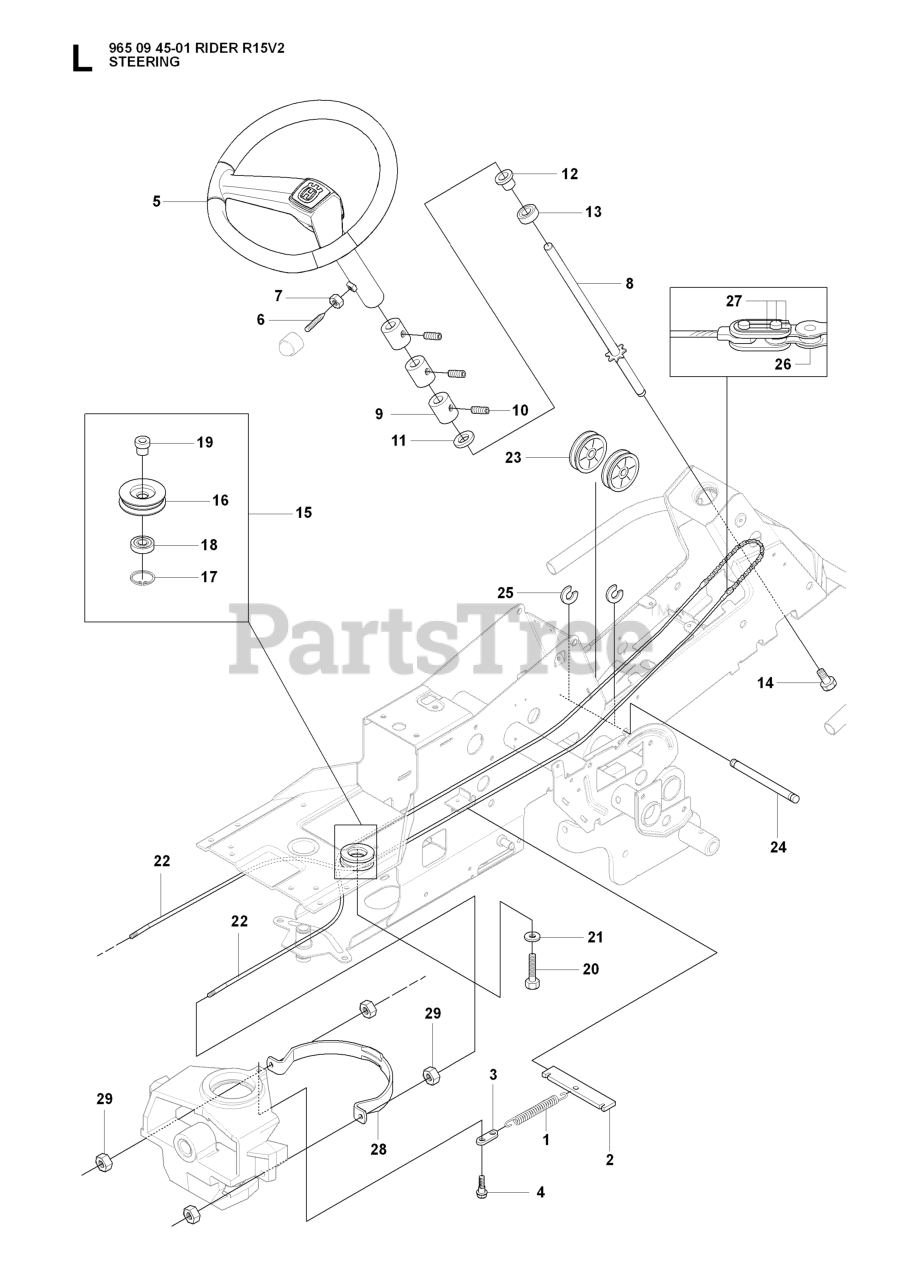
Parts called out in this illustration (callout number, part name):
2	SPRING BRACKET
5	STEERING WHEEL
7	NUT
8	ROD STEERING ASSY
9	SPACER
13	BALL BEARING 6004-2RS1
17	CIRCLIP SGH 47
18	BALL-BEARING 6204-2RS
22	RP STEERING CABLE COMPLETE
25	RETAINING RING
26	STEERING CHAIN
28	WIRE GUIDE
29	NUT
